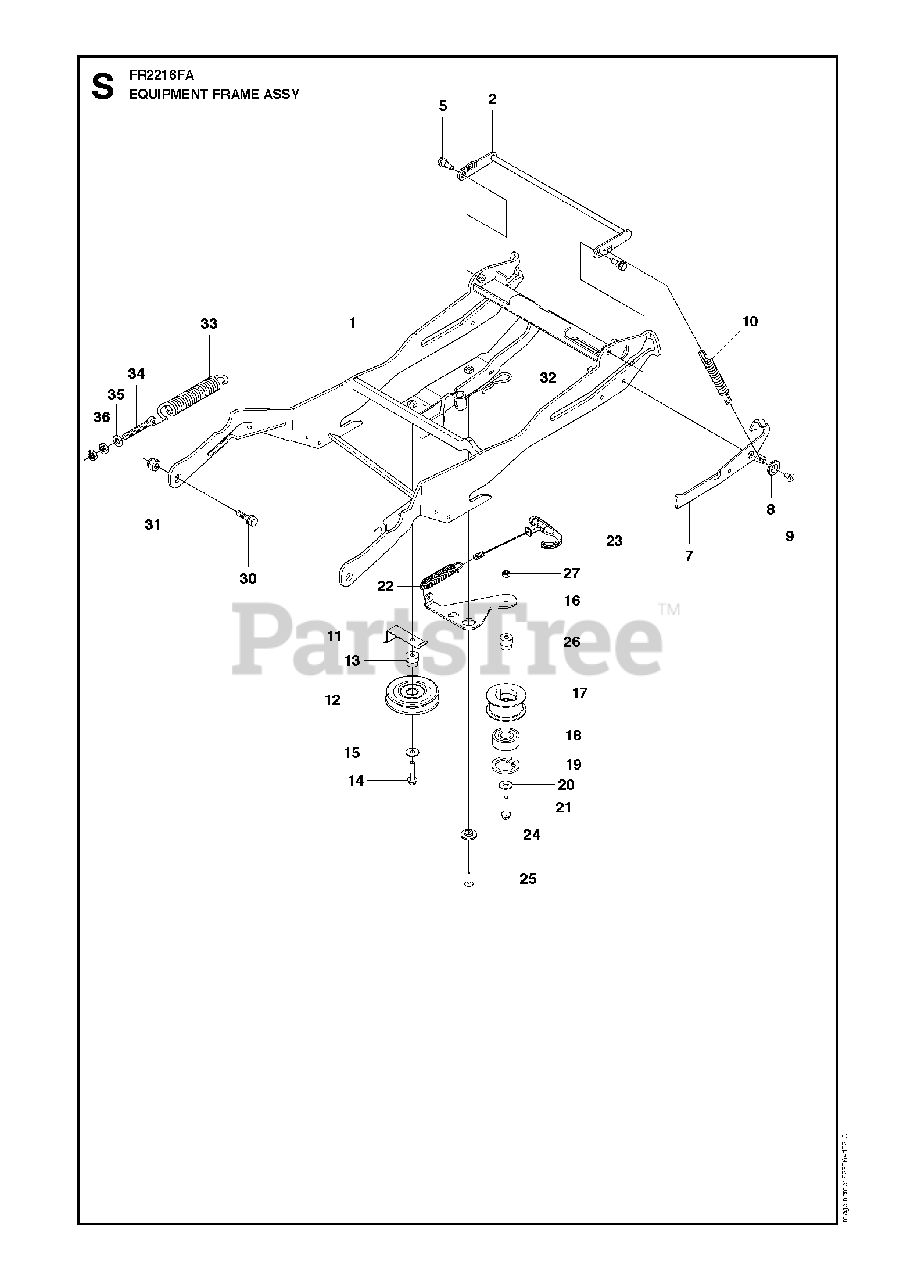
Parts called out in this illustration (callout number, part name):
9	SCREW IHCSFM
10	REPL BY 506 54 25-01
11	BELT GUIDE
17	%PULLEY
18	BALL BEARING 6004-2RS1
19	RETAINING RING
23	HANDLE ASSY
24	WASHER
27	LOCKNUT M8
35	WASHER
